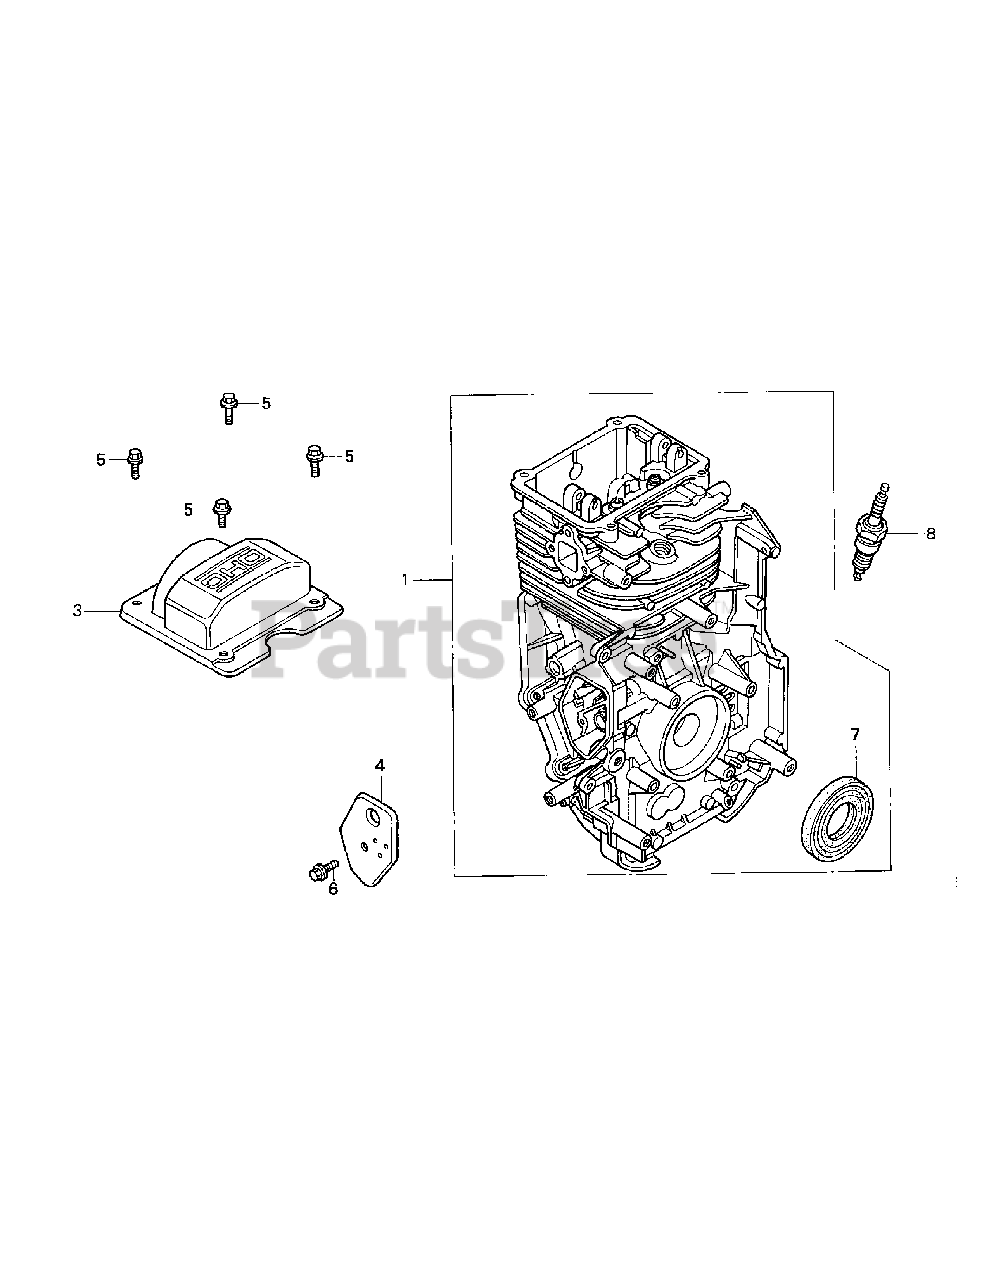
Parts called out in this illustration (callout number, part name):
1	Cylinder Assembly, 010
3	Head Cover
4	Breather Cover (Valve Assembly)
5	Flange Bolt, 6 x 12
6	Flange Bolt, 6 x 14
7	Oil Seal, 25.4 x 62 x 6
8	Spark Plug (BPR6ES NGK)
